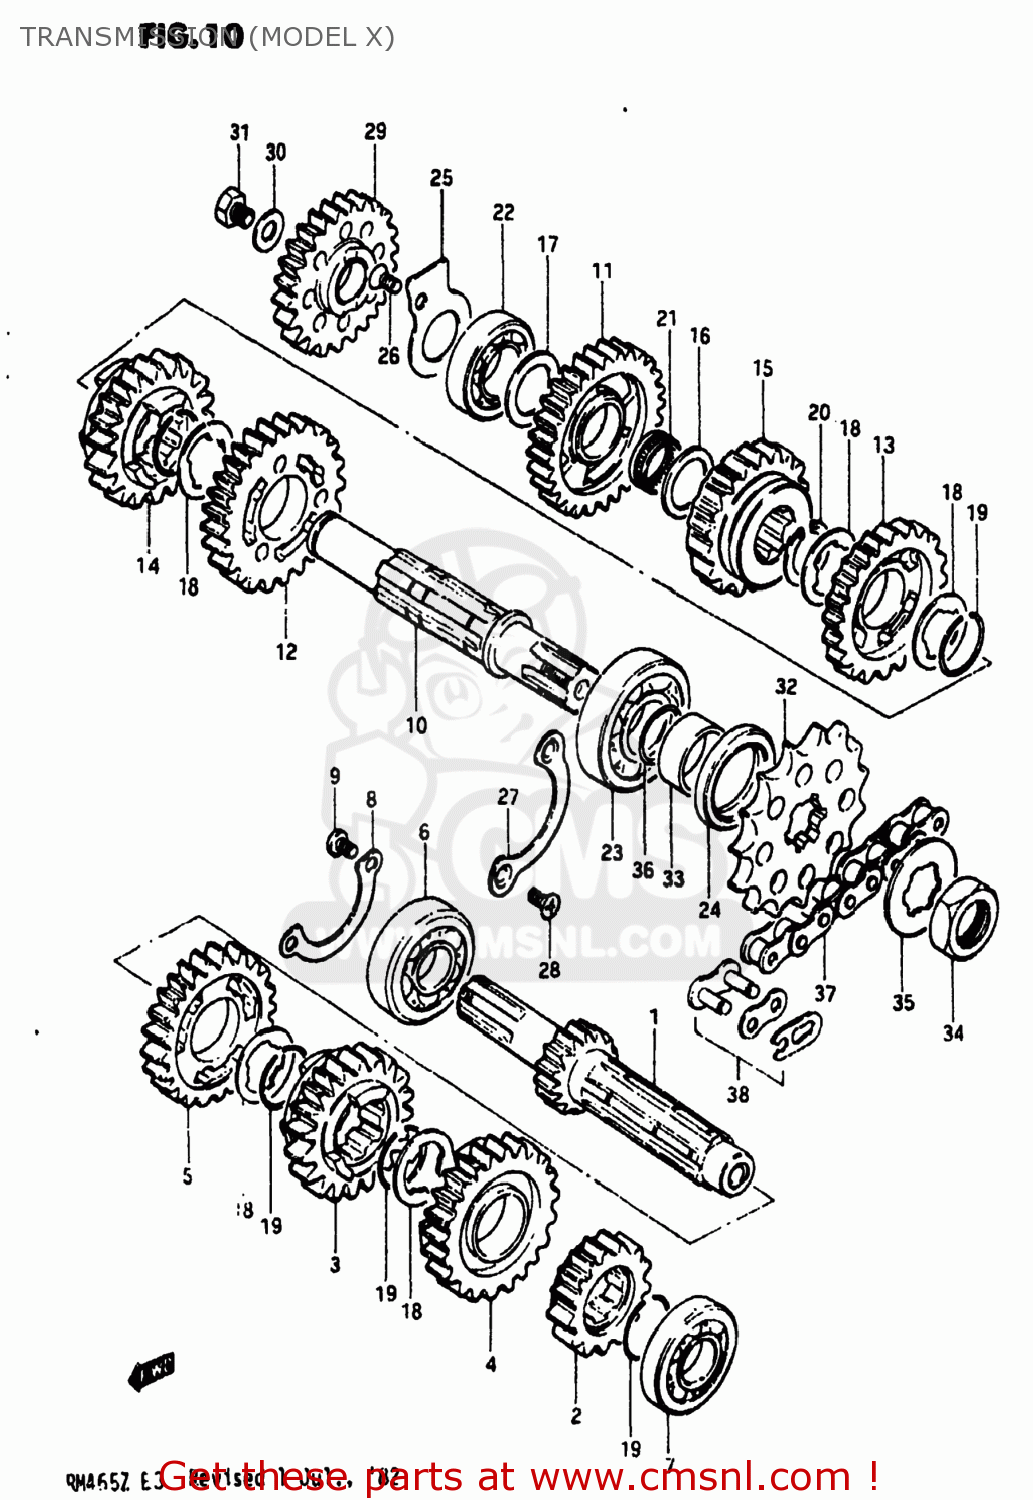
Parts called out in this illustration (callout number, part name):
1	SHAFT,COUNTER
2	GEAR,SECOND DRIVE
3	GEAR,THIRD DRIVE
4	GEAR,FOURTH DRIVE
5	GEAR,FIFTH DRIVE
6	BEARING
7	BEARING, LH
8	RETAINER,BEARING
9	SCREW 6X12
10	SHAFT,DRIVE
11	GEAR,FIRST DRIVEN
12	GEAR,SECOND DRIVEN
13	GEAR,THIRD DRIVEN
14	GEAR,FOURTH DRIVEN
15	GEAR,FIFTH DRIVEN
16	WASHER
17	WASHER
18	WASHER,LOCK
19	RING,SNAP
20	CIRCLIP
21	BEARING(20X24X10).8
22	BEARING
23	BEARING(22X56X16)
24	SEAL,OIL(32X42X6)
25	RETAINER,DRIVESHAFT
26	SCREW
27	PLATE,DRIVESHAFT BEARING
28	SCREW
29	GEAR,KICK STARTER IDLE
30	WASHER,THRUST
31	BOLT
32	SPROCKET,ENGINE
33	SPACER(22X32X11.5)
34	NUT
35	WASHER,LOCK
36	O RING(D:1.7,ID:22)
37	CHAIN ASSEMBLY,DRIVE
38	JOINT ASSEMBLY,CHAIN
